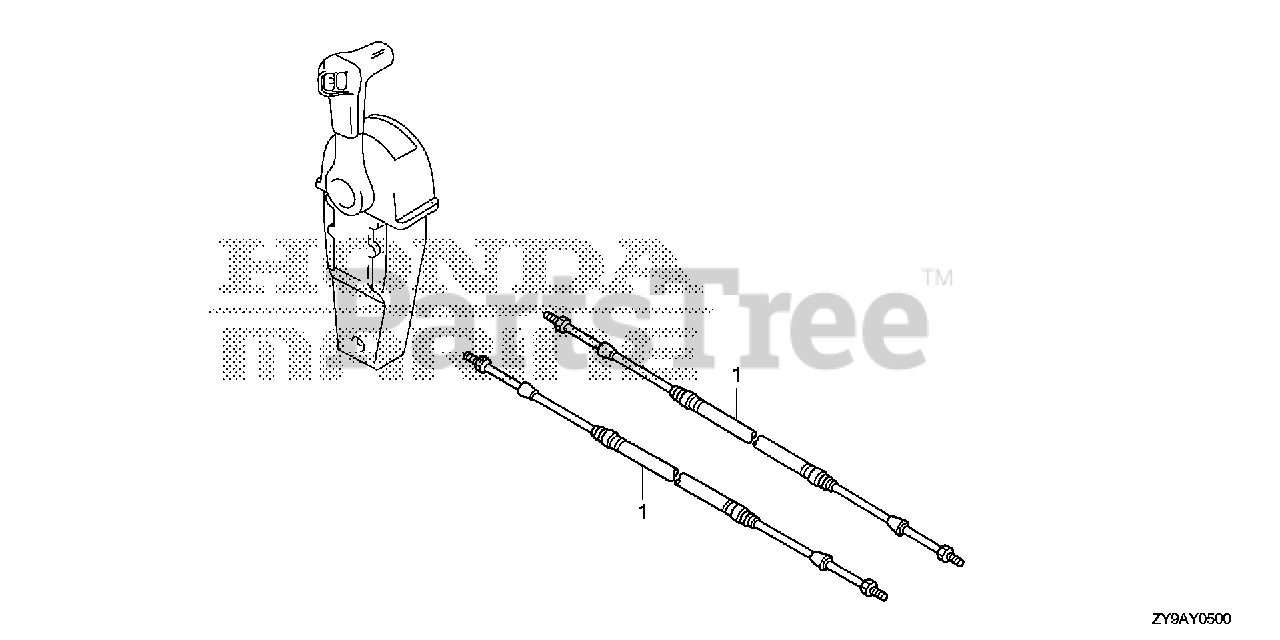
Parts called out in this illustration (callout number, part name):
1	CABLE, REMOTE CONTROL (10') (LOW FRICTION)
1	CABLE ASSY., PUSH-PULL (33C-5FT)
1	CABLE, REMOTE CONTROL (11') (LOW FRICTION)
1	CABLE ASSY., PUSH-PULL (33C-6FT)
1	CABLE, REMOTE CONTROL (12') (LOW FRICTION)
1	CABLE ASSY., PUSH-PULL (33C-7FT)
1	CABLE, REMOTE CONTROL (13') (LOW FRICTION)
1	CABLE ASSY., PUSH-PULL (33C-8FT)
1	CABLE, REMOTE CONTROL (14') (LOW FRICTION)
1	CABLE ASSY., PUSH-PULL (33C-9FT)
1	CABLE, REMOTE CONTROL (15') (LOW FRICTION)
1	CABLE ASSY., PUSH-PULL (33C-10FT)
1	CABLE, REMOTE CONTROL (16') (LOW FRICTION) (NOT AVAILABLE)
1	CABLE ASSY., PUSH-PULL (33C-11FT)
1	CABLE, REMOTE CONTROL (17') (LOW FRICTION)
1	CABLE ASSY., PUSH-PULL (33C-12FT)
1	CABLE, REMOTE CONTROL (18') (LOW FRICTION) (NOT AVAILABLE)
1	CABLE ASSY., PUSH-PULL (33C-13FT)
1	CABLE, REMOTE CONTROL (19') (LOW FRICTION)
1	CABLE ASSY., PUSH-PULL (33C-14FT)
1	CABLE, REMOTE CONTROL (20') (LOW FRICTION) (NOT AVAILABLE)
1	CABLE ASSY., PUSH-PULL (33C-15FT)
1	CABLE, REMOTE CONTROL (21') (LOW FRICTION)
1	CABLE ASSY., PUSH-PULL (33C-16FT)
1	CABLE, REMOTE CONTROL (22') (LOW FRICTION) (NOT AVAILABLE)
1	CABLE ASSY., PUSH-PULL (33C-17FT)
1	CABLE, REMOTE CONTROL (23') (LOW FRICTION)
1	CABLE ASSY., PUSH-PULL (33C-18FT)
1	CABLE, REMOTE CONTROL (24') (LOW FRICTION) (NOT AVAILABLE)
1	CABLE ASSY., PUSH-PULL (33C-19FT)
1	CABLE, REMOTE CONTROL (25') (LOW FRICTION)
1	CABLE ASSY., PUSH-PULL (33C-20FT)
1	CABLE, REMOTE CONTROL (26') (LOW FRICTION)
1	CABLE ASSY., PUSH-PULL (33C-21FT)
1	CABLE, REMOTE CONTROL (27') (LOW FRICTION)
1	CABLE ASSY., PUSH-PULL (33C-22FT)
1	CABLE, REMOTE CONTROL (28') (LOW FRICTION) (NOT AVAILABLE)
1	CABLE ASSY., PUSH-PULL (33C-23FT)
1	CABLE, REMOTE CONTROL (29') (LOW FRICTION)
1	CABLE ASSY., PUSH-PULL (33C-24FT)
1	CABLE, REMOTE CONTROL (30') (LOW FRICTION) (NOT AVAILABLE)
1	CABLE ASSY., PUSH-PULL (33C-25FT)
1	CABLE, REMOTE CONTROL (31') (LOW FRICTION)
1	CABLE ASSY., PUSH-PULL (33C-26FT)
1	CABLE, REMOTE CONTROL (32') (LOW FRICTION) (NOT AVAILABLE)
1	CABLE ASSY., PUSH-PULL (33C-27FT)
1	CABLE, REMOTE CONTROL (33') (LOW FRICTION)
1	CABLE ASSY., PUSH-PULL (33C-28FT)
1	CABLE, REMOTE CONTROL (34') (LOW FRICTION) (NOT AVAILABLE)
1	CABLE ASSY., PUSH-PULL (33C-29FT)
1	CABLE, REMOTE CONTROL (35') (LOW FRICTION)
1	CABLE ASSY., PUSH-PULL (33C-30FT)
1	CABLE ASSY., PUSH-PULL (33C-31FT)
1	CABLE ASSY., PUSH-PULL (33C-32FT)
